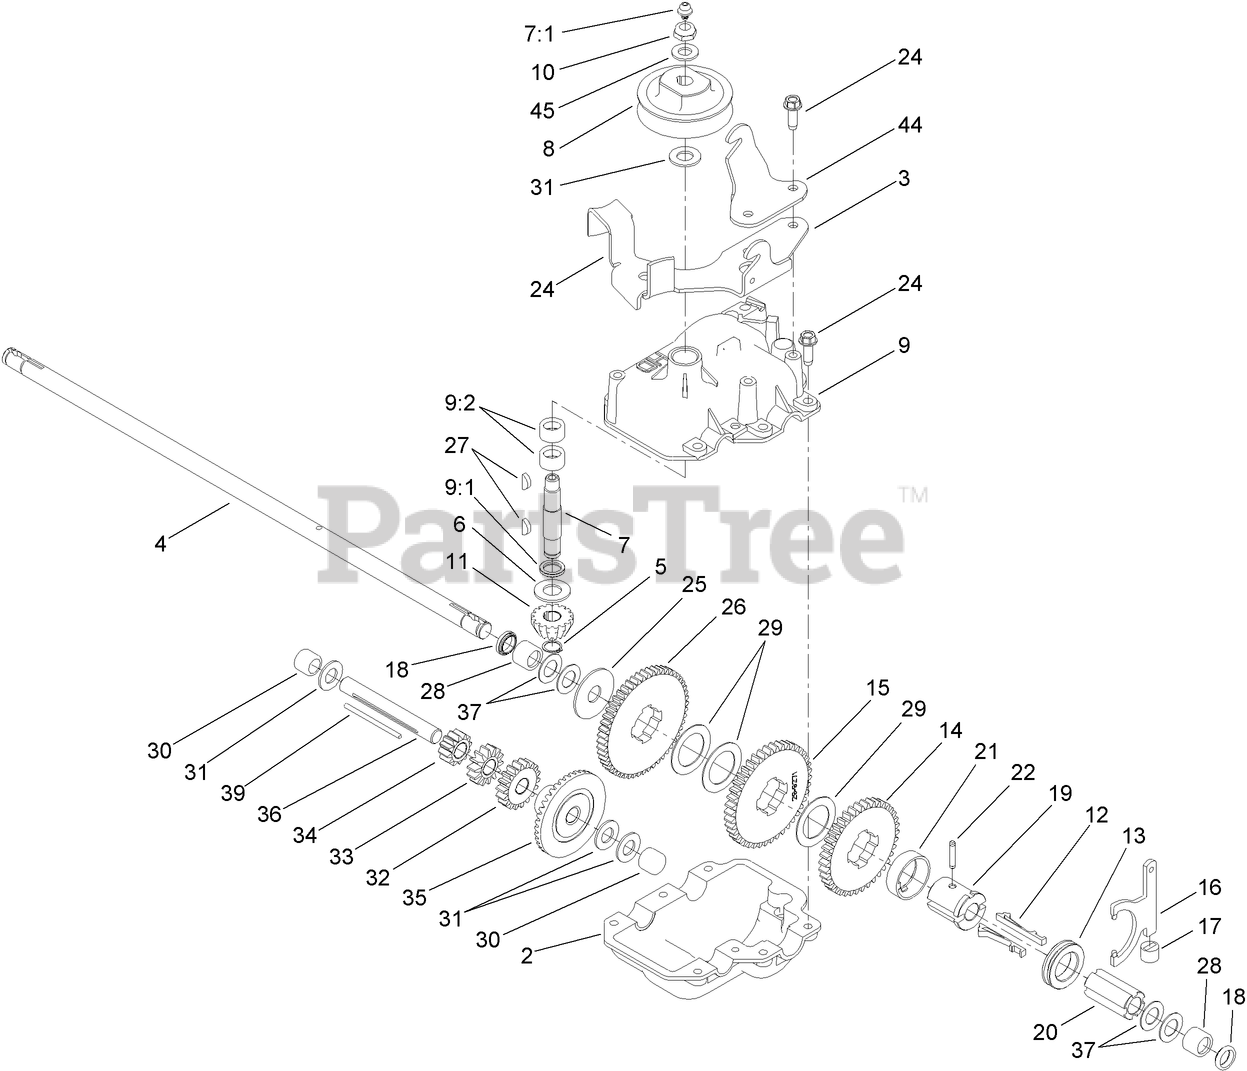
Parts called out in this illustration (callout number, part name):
2	GEARCASE-LOWER
3	BRACKET-GUIDE, BELT
4	SHAFT-OUTPUT
5	RING-RETAINING
6	WASHER-THRUST
7	INPUT SHAFT ASM
7:1	FITTING-GREASE, ZERK
8	PULLEY
9	UPPER GEARCASE ASM
9:2	BEARING-NEEDLE
10	NUT-HEX
11	PINION-BEVEL
12	KEY-SHIFT
13	COLLAR-SHIFT
14	GEAR-38T
15	GEAR-42T
16	YOKE-SHIFT
17	BUSHING-YOKE
18	SEAL-OIL
19	SLEEVE-GEAR
20	SLEEVE
21	RETAINER-KEY
22	PIN-GROOVE
24	SCREW-HWHTF
25	WASHER
27	KEY-WOODRUFF
28	BEARING-CAGED NEEDLE ROLLER
29	WASHER
30	BEARING-NEEDLE, CLOSED
31	WASHER-THRUST
32	GEAR-18T
33	GEAR-14T
34	GEAR-12T
35	GEAR-BEVEL
36	SHAFT-INTERMEDIATE
37	WASHER-PLAIN
44	BRACKET-ENGAGE, TRACTION
45	WASHER-FLAT
